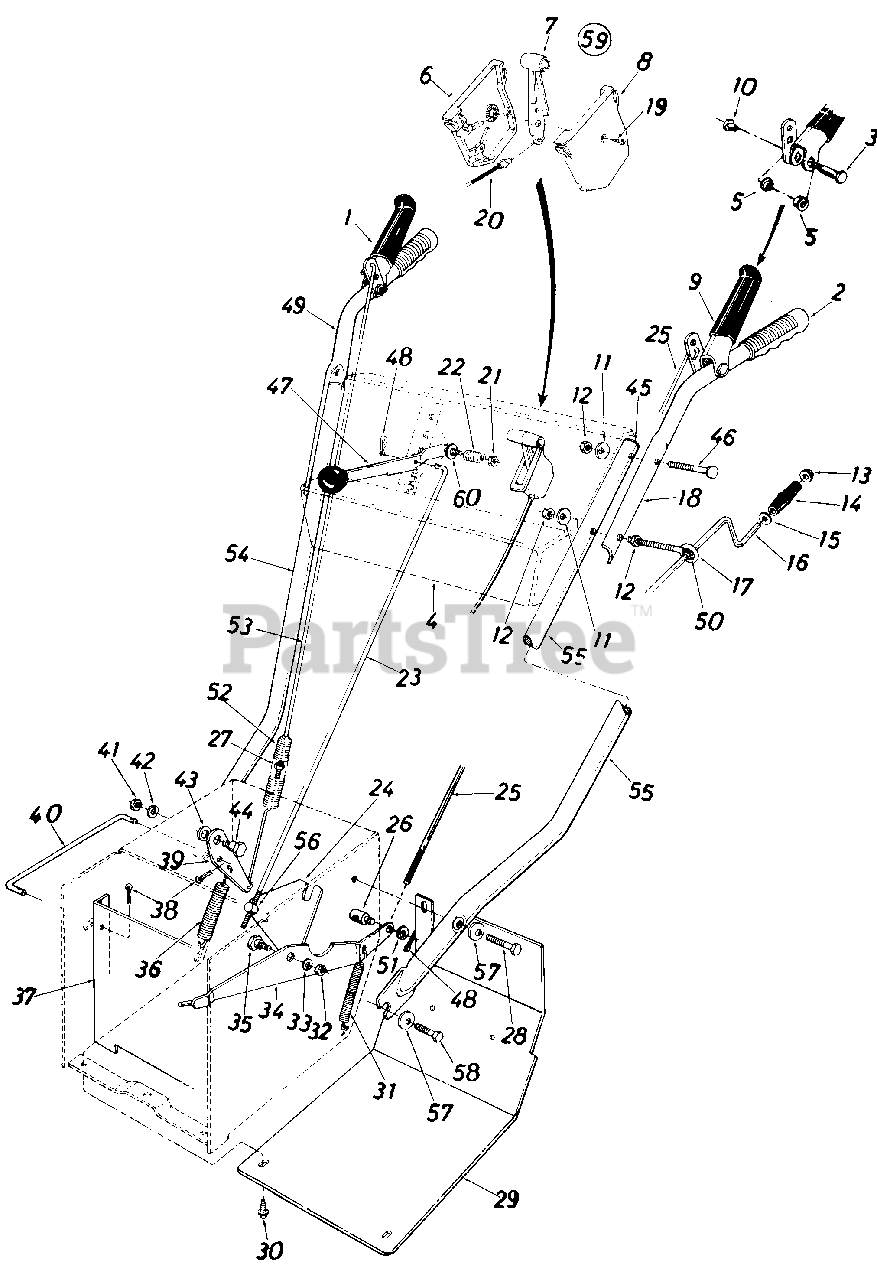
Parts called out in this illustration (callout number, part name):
1	Clutch Grip Ass'y.-R.H.
2	Grip
3	Shoulder Bolt .374 Dia. x 1.53" Lg.
4	Handle Panel Ass'y.
5	Hex Flange Plastic Bearing .380" I.D.
9	Clutch Grip Ass'y.-L.H.
10	Shoulder Nut 1/4-20 Thd.
11	Bell-Wash. .34" I.D. x .88" O.D.
12	Hex Nut 5/16-18 Thd.*
13	Push Nut 3/8" Rod
14	Knob 3/8" Rod
15	Fl-Wash. .40" I.D. x .62" O.D.
16	Chute Crank Ass'y.
17	Eye Bolt 5/16-18 x 5.0" Lg.
18	Upper Handle-L.H.
20	Throttle Control Wire
21	Hex Ins. Jam L-Nut 3/8-24 Thd.
22	Compression Spring .50" O.D. x .88" Lg.
23	Shifting Rod 5/16" x 32.50" Lg.
24	Shifting Linkage Bracket
25	Lockout Rod .214" Dia. x 36.0" Lg.
26	Adjustment Ferrule 1/4-20
27	Hex Ins. L-Nut 1/4-20 Thd.
28	Hex Bolt 3/8-16 x 2.00" Lg.*
29	Frame Cover
30	Hex Wash. Self-Tap Scr. 1/4 -20 x .50" Lg.
31	Extension Spring .38" O.D. x 3.25" Lg.
32	Hex Jam Nut 3/8-16 Thd.*
33	L-Wash. 3/8" I.D.*
34	Auger Clutch Bracket Ass'y.
35	Shld. Bolt .625" Dia. x .170
36	Extension Spring .75" O.D. x 4.31 " Lg.
37	Drive Pulley Support Brkt. Ass'y.
38	Cotter Pin 3/32" Dia. x .75" Lg.
39	Drive Clutch Bracket
40	Drive Clutch Rod
41	Hex Jam Nut 3/8-16 Thd.*
42	L-Wash. 3/8" I.D.*
43	Fl-Wash. .34" I.D. x .75" O.D.
44	Shld. Bolt .625" Dia. x .170
45	Plastic Plug
46	Carriage Bolt 5/16-18 x 2.0" Lg.
47	Shift Handle Ass'y.
48	Int. Cotter Pin 5116" Dia.
49	Upper Handle-R.H.
50	Grommet
51	Fl-Wash. .28" I.D. x .62" O.D.
52	Extension Spring .75" O.D. x 5.00" Lg.
53	Lockout Rod .214" Dia. x 32" Lg.
54	Lower Handle-R.H.
55	Lower Handle-L.H.
56	Adjustment Ferrule
57	Bell-Wash. .40" I.D. x .88" O.D.
58	Hex Wash. Self-Tap Scr. 3/8-16 x .75" Lg.
59	Throttle Control Box Ass'y.
60	Bell-Wash. .40" I.D. x .88" O.D.
